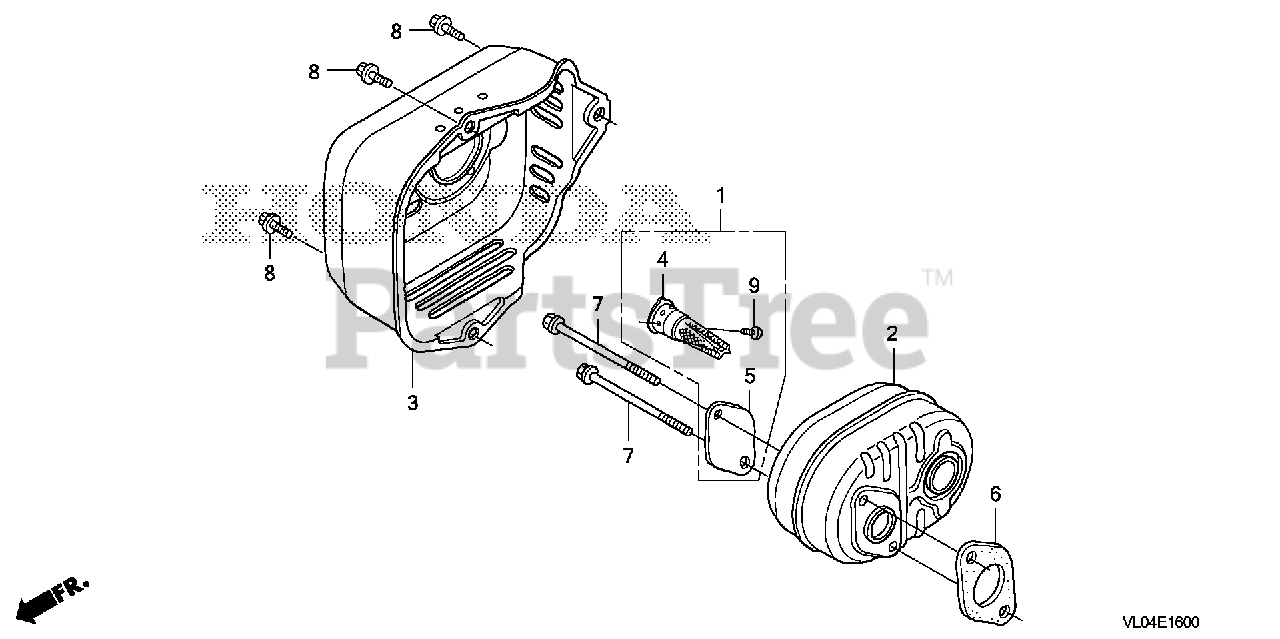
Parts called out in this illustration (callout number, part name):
1	ARRESTER KIT, SPARK
2	MUFFLER
3	PROTECTOR, MUFFLER
4	ARRESTER, SPARK
5	PLATE, ARRESTER NUMBER
6	GASKET, MUFFLER
7	BOLT, FLANGE (6X79) (CT200)
8	BOLT, FLANGE (6X12) (CT200)
9	SCREW, TAPPING (4X6)
